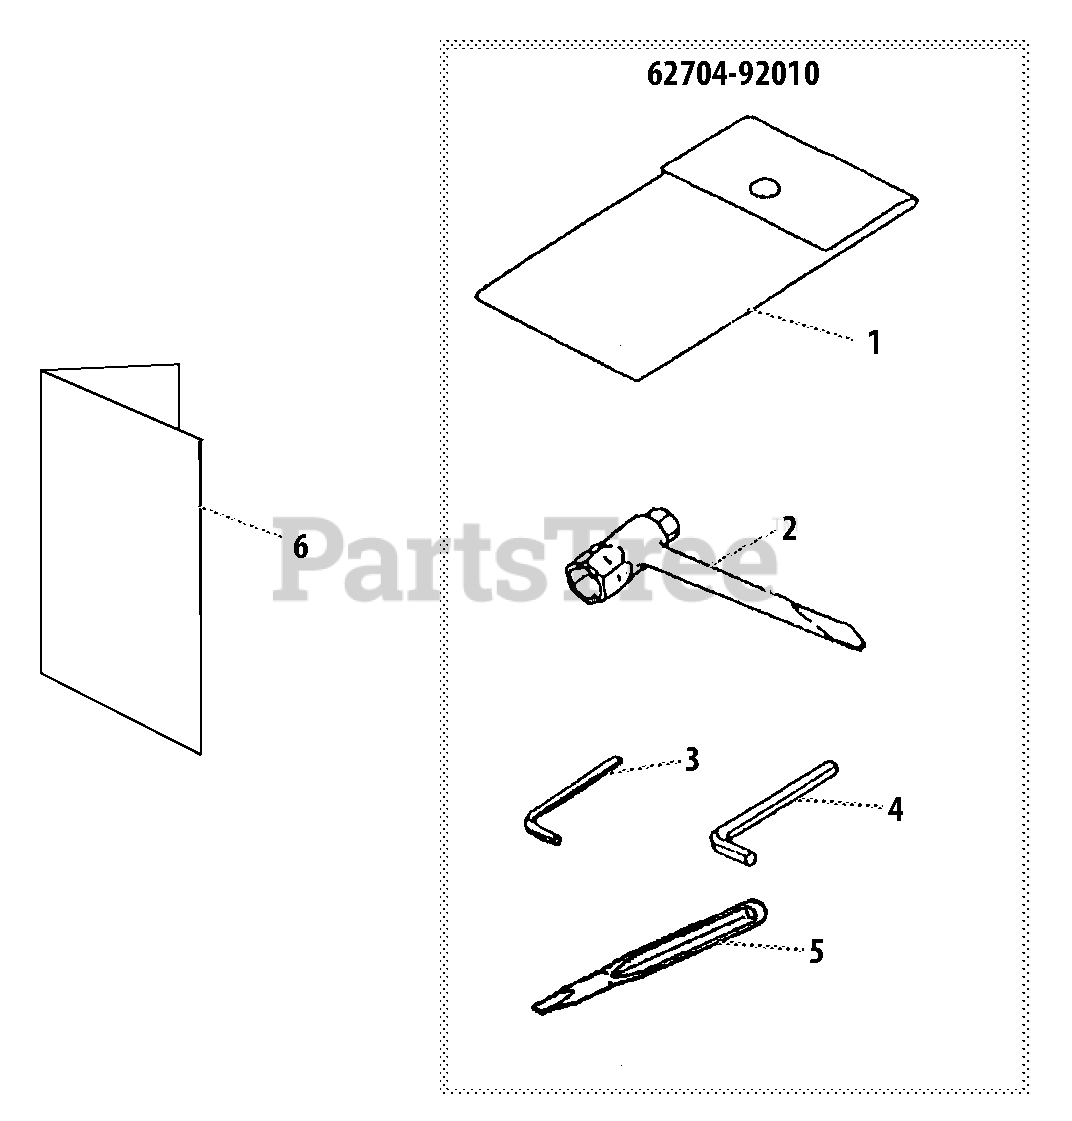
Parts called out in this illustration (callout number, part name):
1	BAG, TOOL
2	T-WRENCH 13×19 MM
3	WRENCH, ALLEN 3 MM
4	WRENCH, ALLEN 4 MM
5	SCREWDRIVER, PLASTIC
6	OWNER'S MANUAL
62704-92010	TOOL KIT, SERVICE
